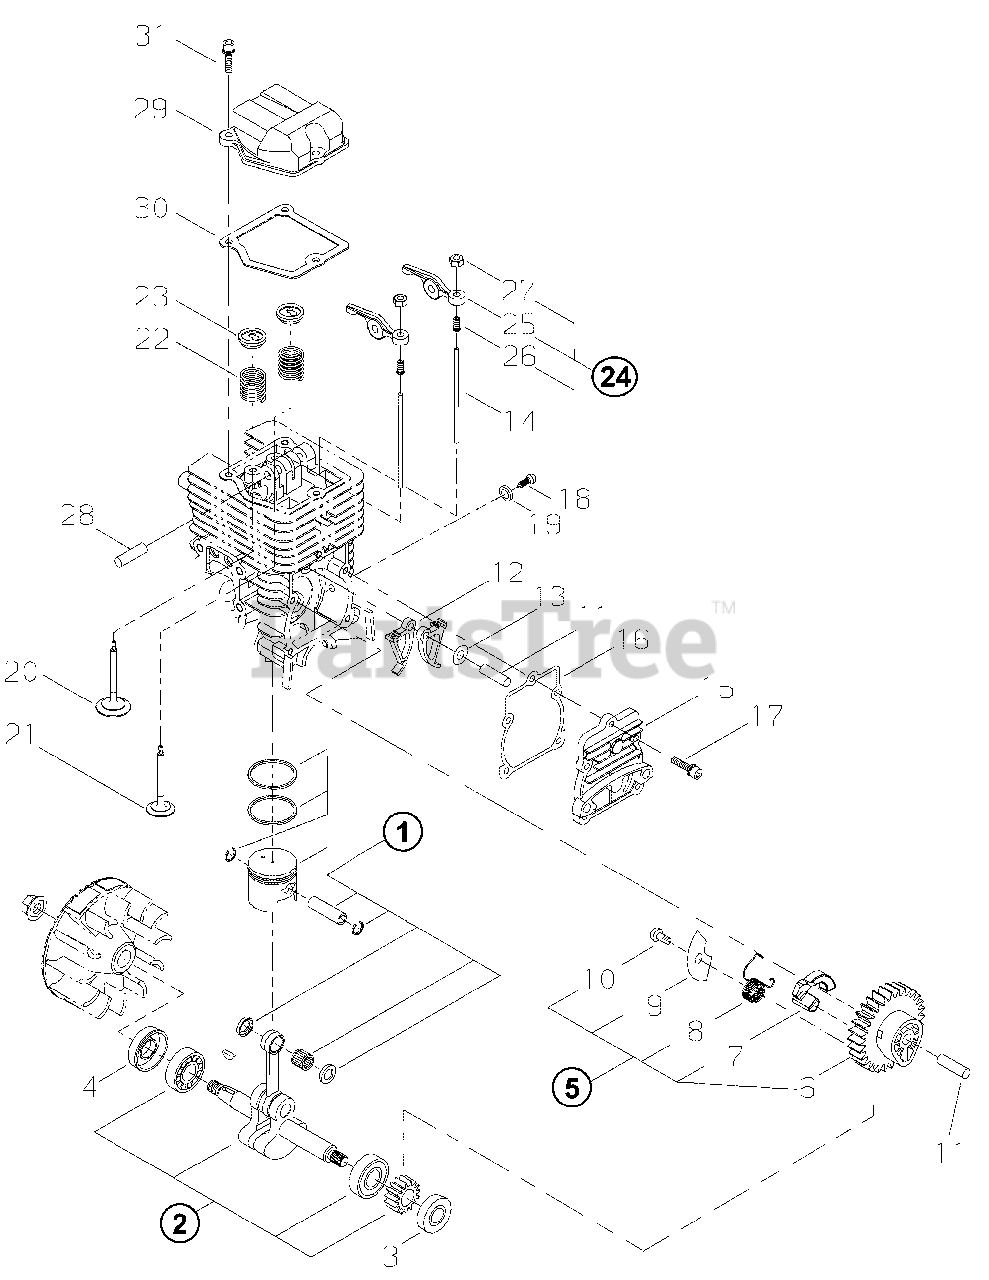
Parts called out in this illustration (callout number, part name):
1	PISTON KIT
2	CRANKSHAFT ASSY
3	SEAL, OIL - 12
4	SEAL, OIL - 12
5	CAM GEAR ASSY
6	GEAR, CAM
7	WEIGHT
8	SPRING
9	PLATE
10	SCREW - 4X6 -- TAPPING
11	PIN - LOCATING
12	FOLLOWER, CAM
13	WASHER - 5
14	PUSHROD
15	COVER, CAM GEAR
16	GASKET
17	SCREW - 4X14
18	SCREW - 5
19	WASHER
20	VALVE, INTAKE
21	VALVE, EXHAUST
22	SPRING, VALVE
23	VALVE RETAINER ASSY
24	ROCKER ARM ASSY
25	ARM, ROCKER
26	SCREW, ADJUST
27	LOCKNUT, ADJUSTER
28	SHAFT, ROCKER ARM - 5X31.8
29	COVER, ROCKER ARM
30	GASKET
31	SCREW - 4X12
